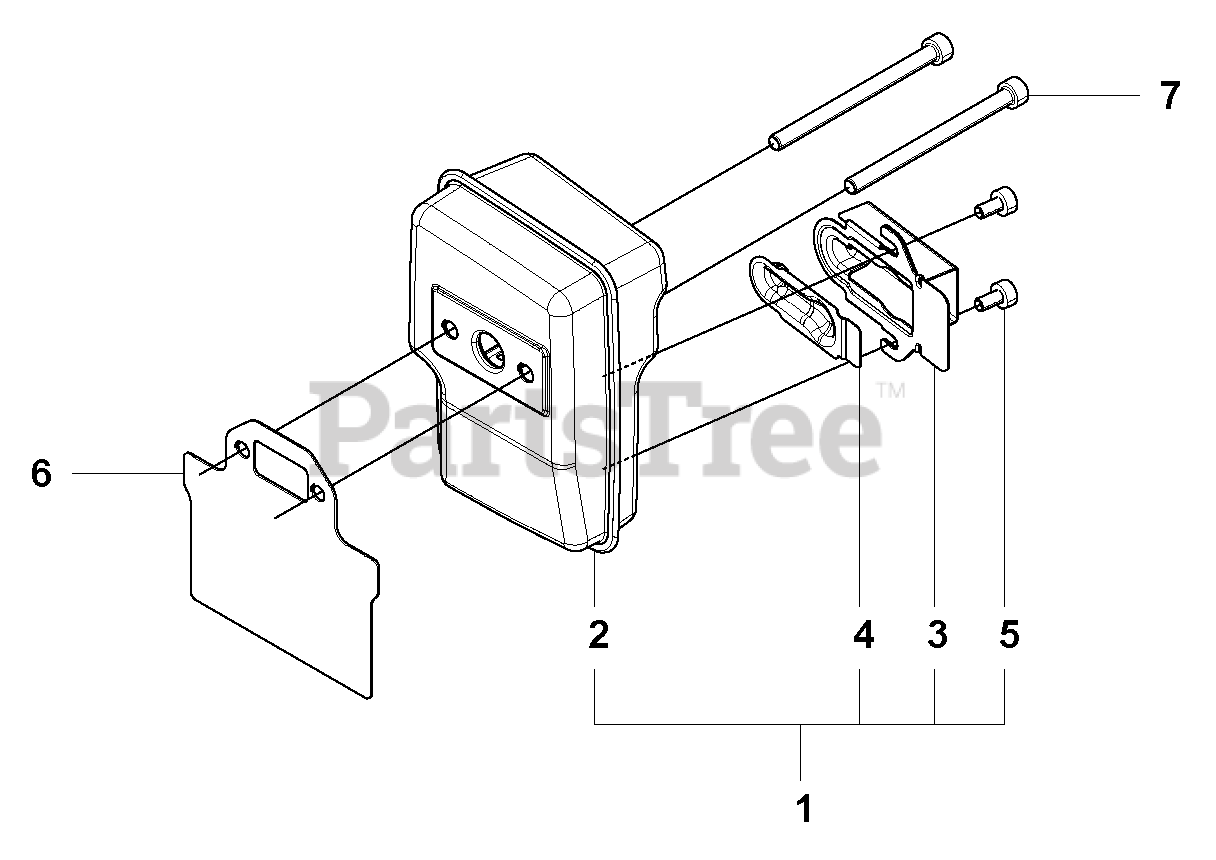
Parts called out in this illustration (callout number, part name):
1	MUFFLER A
2	MUFFLER A
3	EXHAUSE DUCT
7	BOLT
